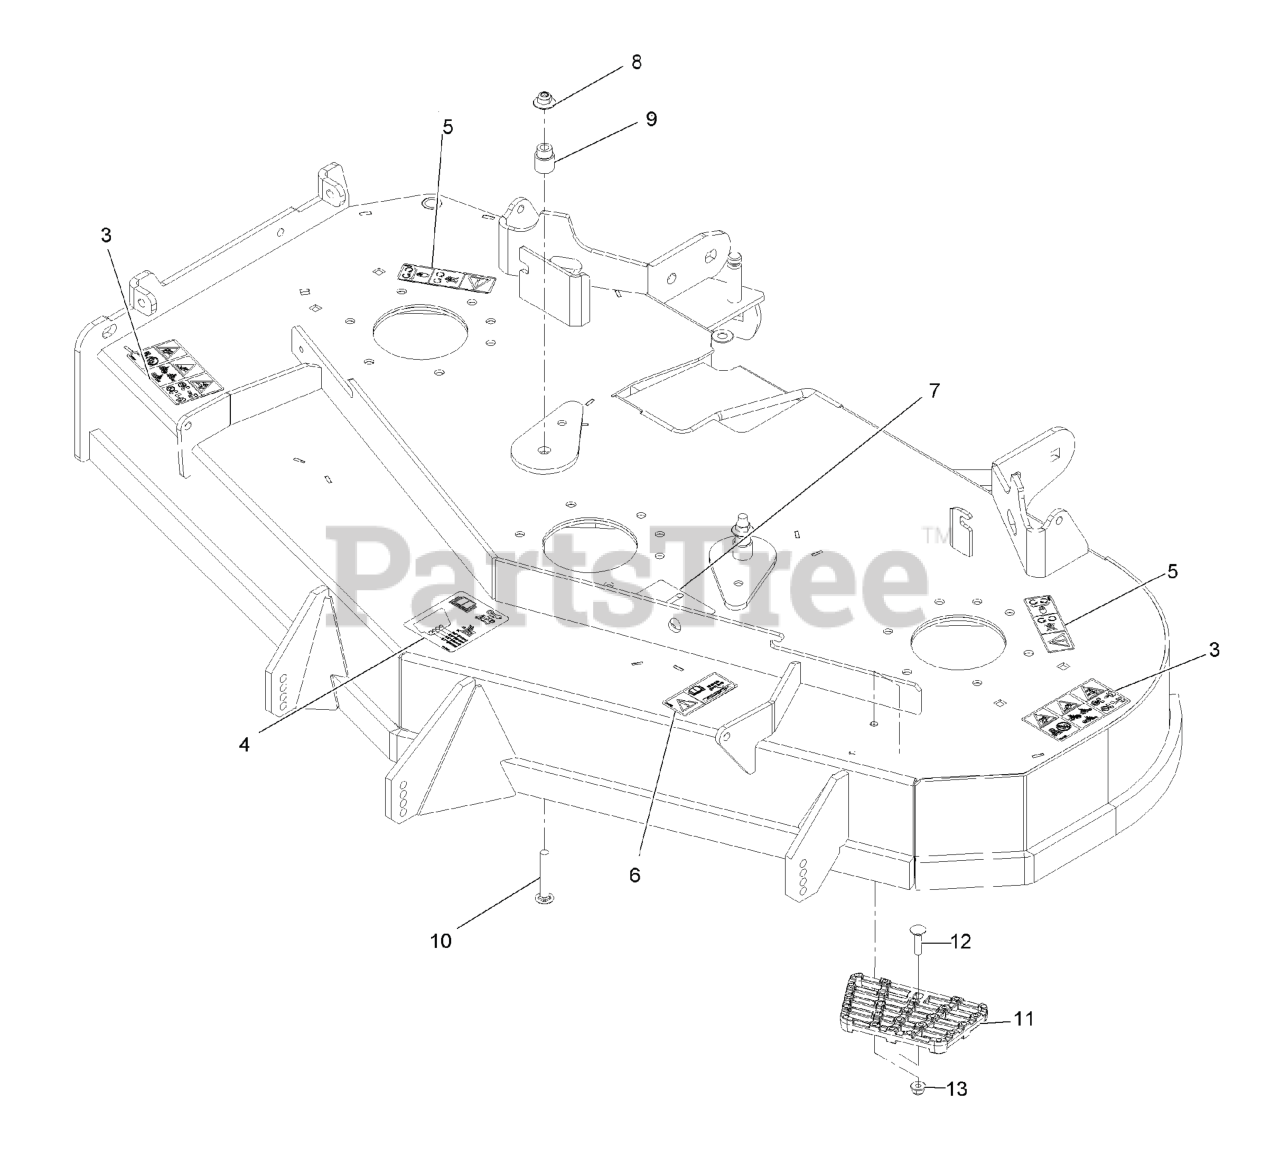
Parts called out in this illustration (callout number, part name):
3	DECAL-DANGER THROWN OBJECTS
4	DECAL-ROLLER, ANTI-SCALP
5	DECAL-COVER, MISSING
6	DECAL-TORQUE, BOLT
7	DECAL-BELT ROUTING
8	Nut-Nyloc 3/8-16 Flg
9	BUSHING-IDLER
10	SCREW-CARR
11	STEP-DECK
12	Bolt-Carriage 5/16-18 X 1 1/4
13	NUT-HF, NI
